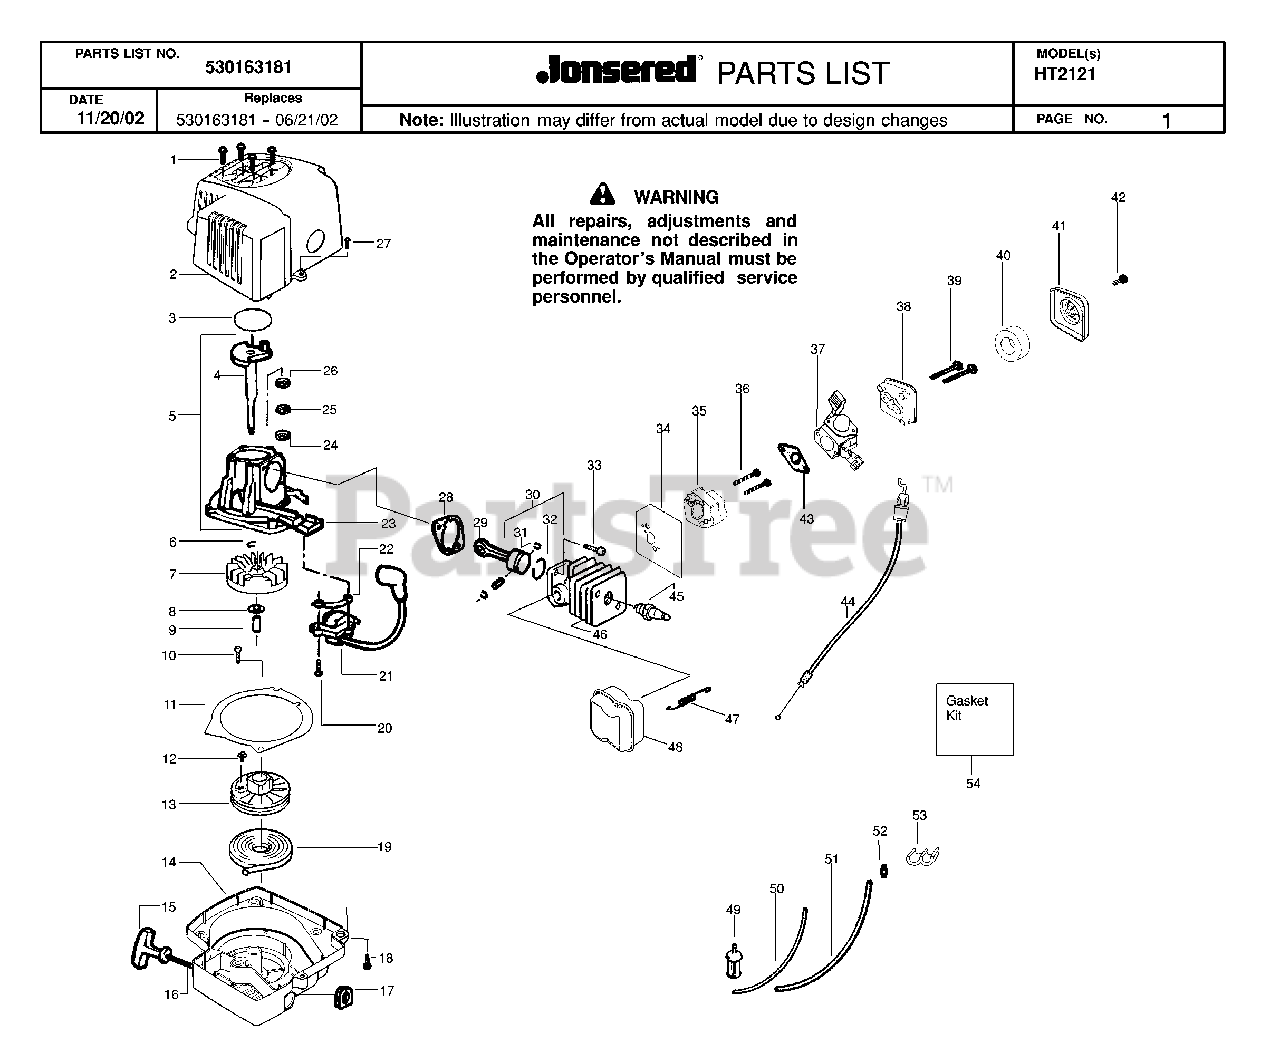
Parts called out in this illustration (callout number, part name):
2	ASSY-SHROUD
3	GASKET KIT
4	CRANKSHAFT
5	CRANK CASE/SHAFT ASSY.
6	RETAINING RING
7	FLYWHEEL
8	WASHER FLAT
10	SCREW-10-16 X 1/2 HI-LO
11	PLATE-BAFFLE
13	STARTER PULLEY
14	FAN HOUSING
15	HANDLE-STARTER
19	STARTER SPRING
21	IGNITION MODULE
22	SPACER - IGNITION MODULE
23	CRANKCASE
24	OUTER BEARING
26	BEARING
28	GASKET KIT
30	PISTON
31	WRIST PIN RET.
32	PISTON RING
34	GASKET KIT
35	ADAPTER-CARBURETOR
36	SCREW - CARB. ADAPTOR
41	AIR FILTER COVER
43	GASKET KIT
44	ASSY-THROTTLE CABLE
45	PLUG-SPARK (RCJ-6Y)
46	KIT-CYLINDER
48	KIT-SPARK MUFFLER
49	ASSY-PICK-UP
52	FUEL LINE FITTING
54	GASKET KIT
530071601	CARBURETOR
530071633	CARBURETOR ASSY (C1U-W13A)
